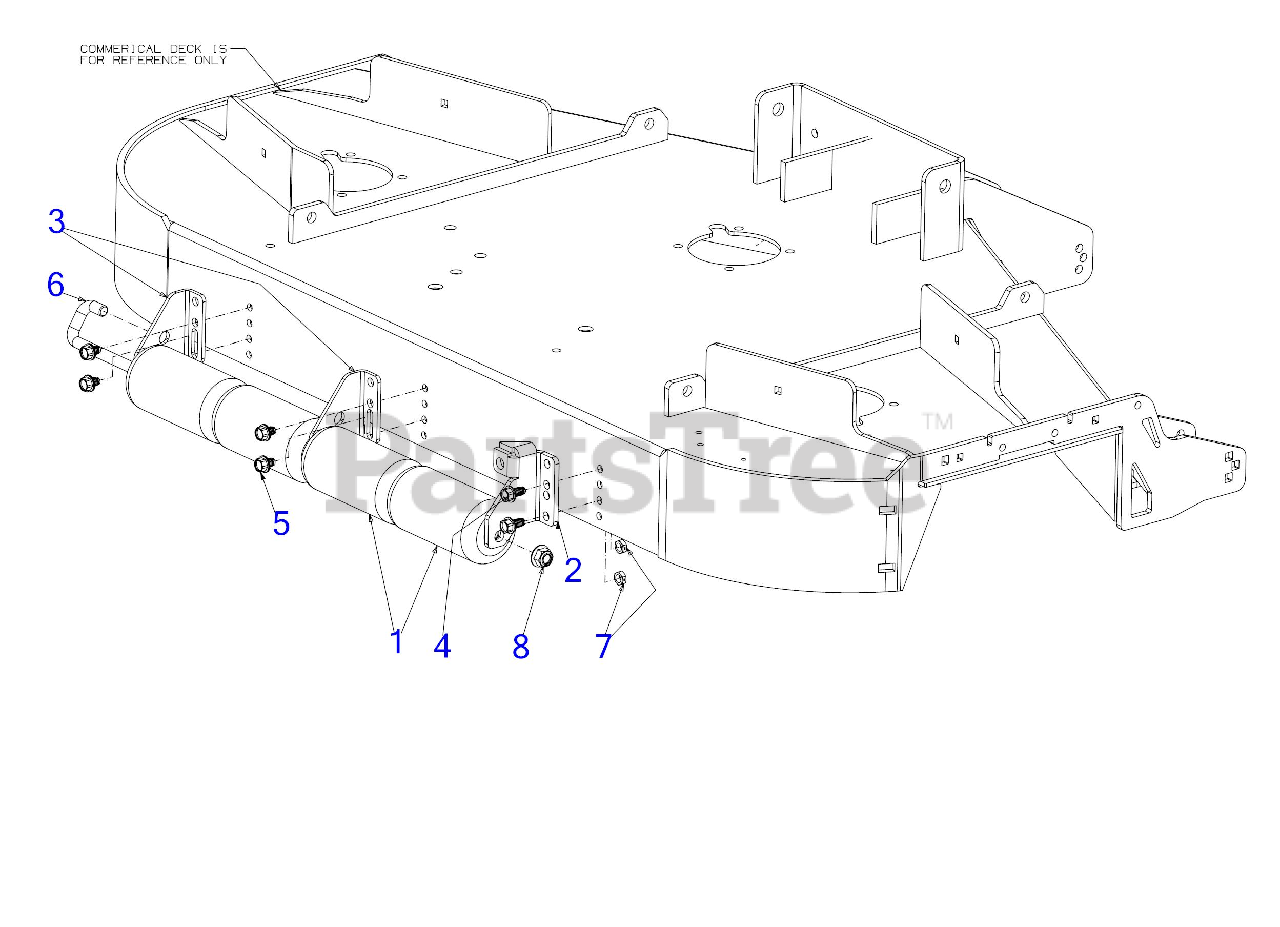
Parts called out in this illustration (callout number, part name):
1	ROLLER ASSEMBLY
4	SCREW 3/8-16 x 3/4
5	SCREW 3/8-16 x .500
6	ROLLER PIN
7	JAM LOCK NUT
